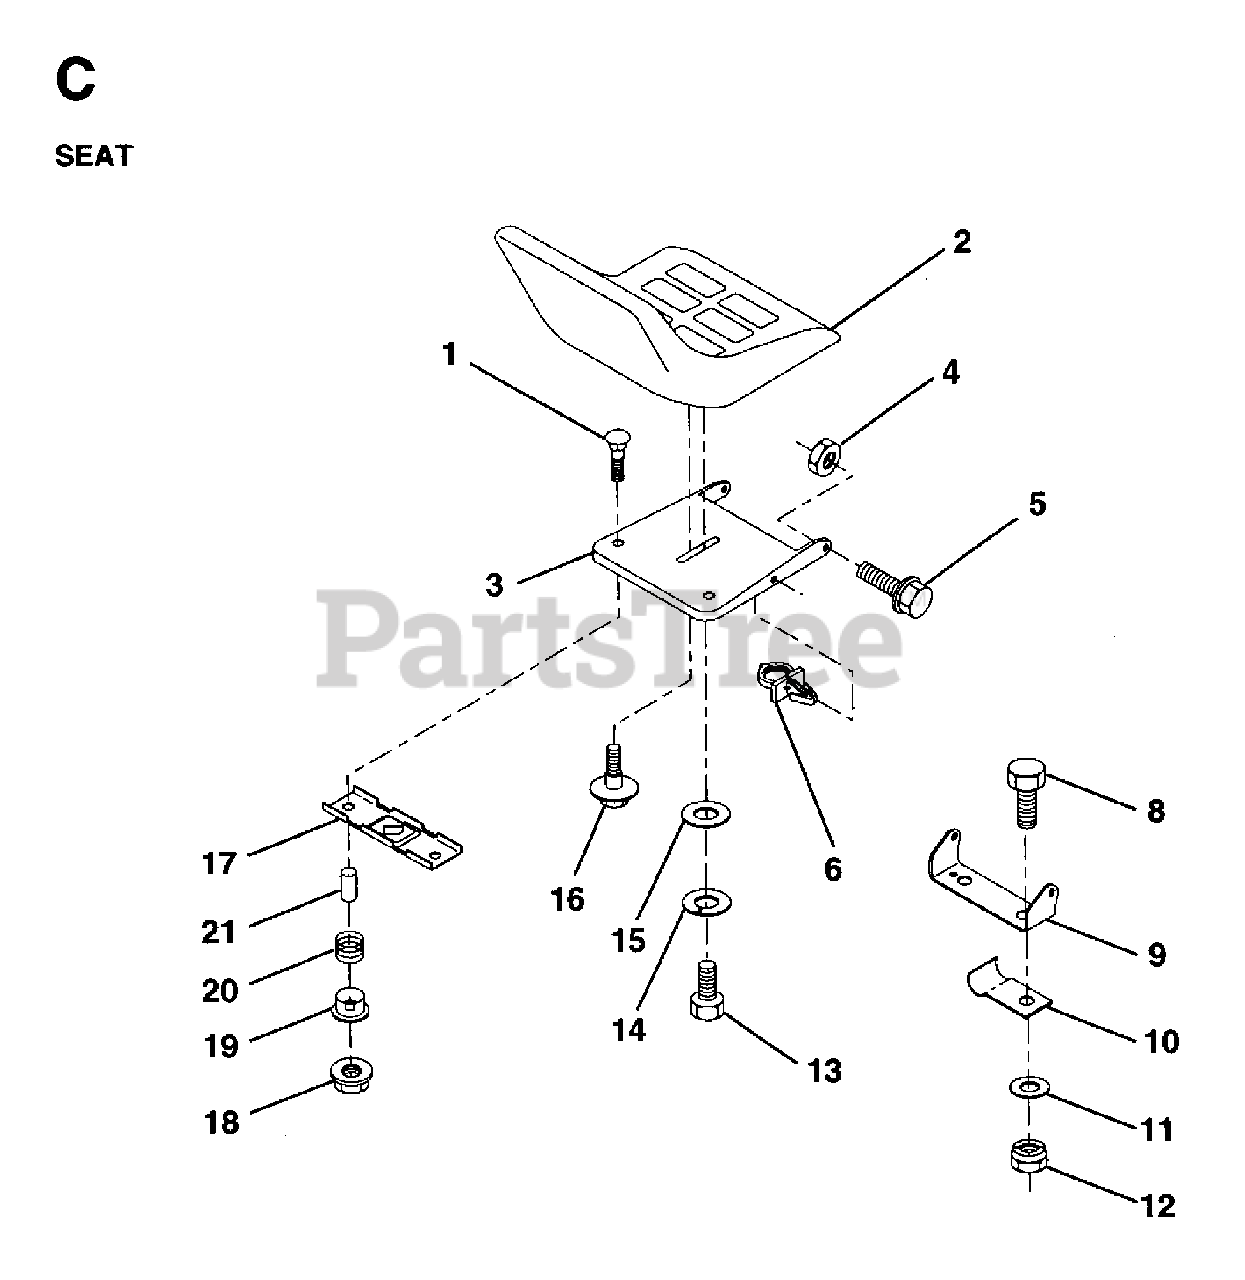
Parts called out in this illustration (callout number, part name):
1	BOLT CARRIAGE 1/4-20X1 3/8
2	SEAT
3	SEAT PAN
4	NUT.71038.31-18.HEX.NYLOCK
5	BOLT SHOULDER 5/16-18
6	PUSH CLIP
8	BOLT
9	SEAT PIVOT BRKT
10	CLIP,INSULATOR
11	WASHER 12/32X2X10GA
12	NUT
13	BOLT
14	LOCKWASHER
16	BOLT,SHOULD
17	BRKT SWITCH
18	NUT T
20	SPRING COMPRESSED
21	SPACER SPLIT
